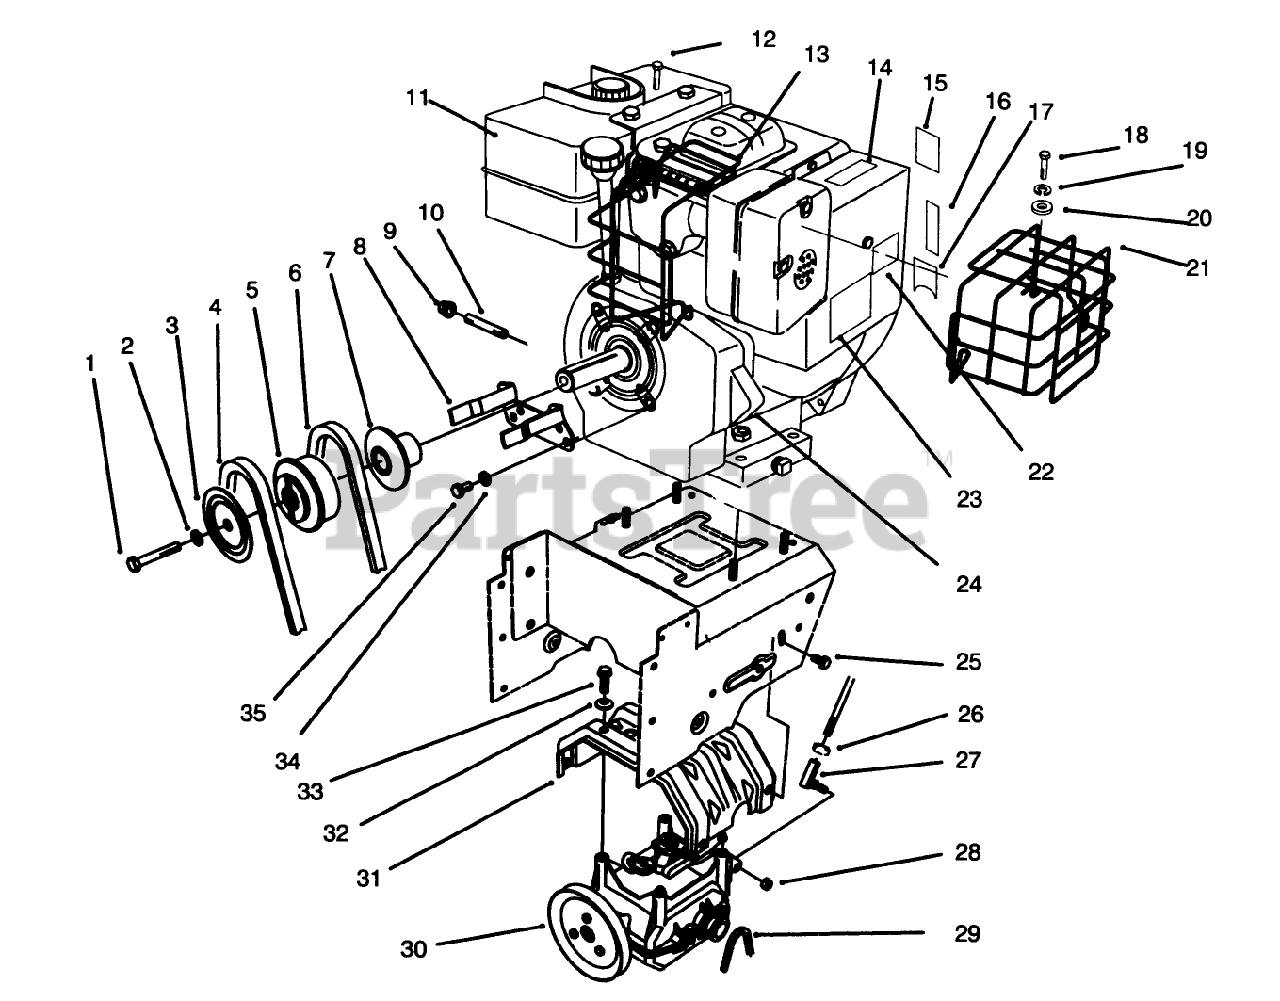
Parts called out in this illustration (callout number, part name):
1	SCREW-HH
2	WASHER-LOCK
3	SHEAVE-HALF, IMPELLER
4	V-BELT
5	PULLEY-ENGINE, CENTER
6	V-BELT, TRACTION
9	CAP-PIPE
10	NIPPLE-PIPE
12	TECH# 650839
13	TECH#36849
15	DECAL - PRIMER
16	DECAL - THROTTLE, INT'L
17	DECAL - CHOKE
18	SCREW
19	TECH# 650979
20	TECH# 650147
21	TECH#36849
22	DECAL-WARNING, HOT SURFACE
23	DECAL-SURFACE, HOT
24	NUT-HF
25	SCREW-HHF
26	SCREW-CARR
28	NUT-LOCK, NI
30	TRACTION GEARCASE ASM
32	WASHER-SPRING
34	WASHER-LOCK
35	SCREW-HH
